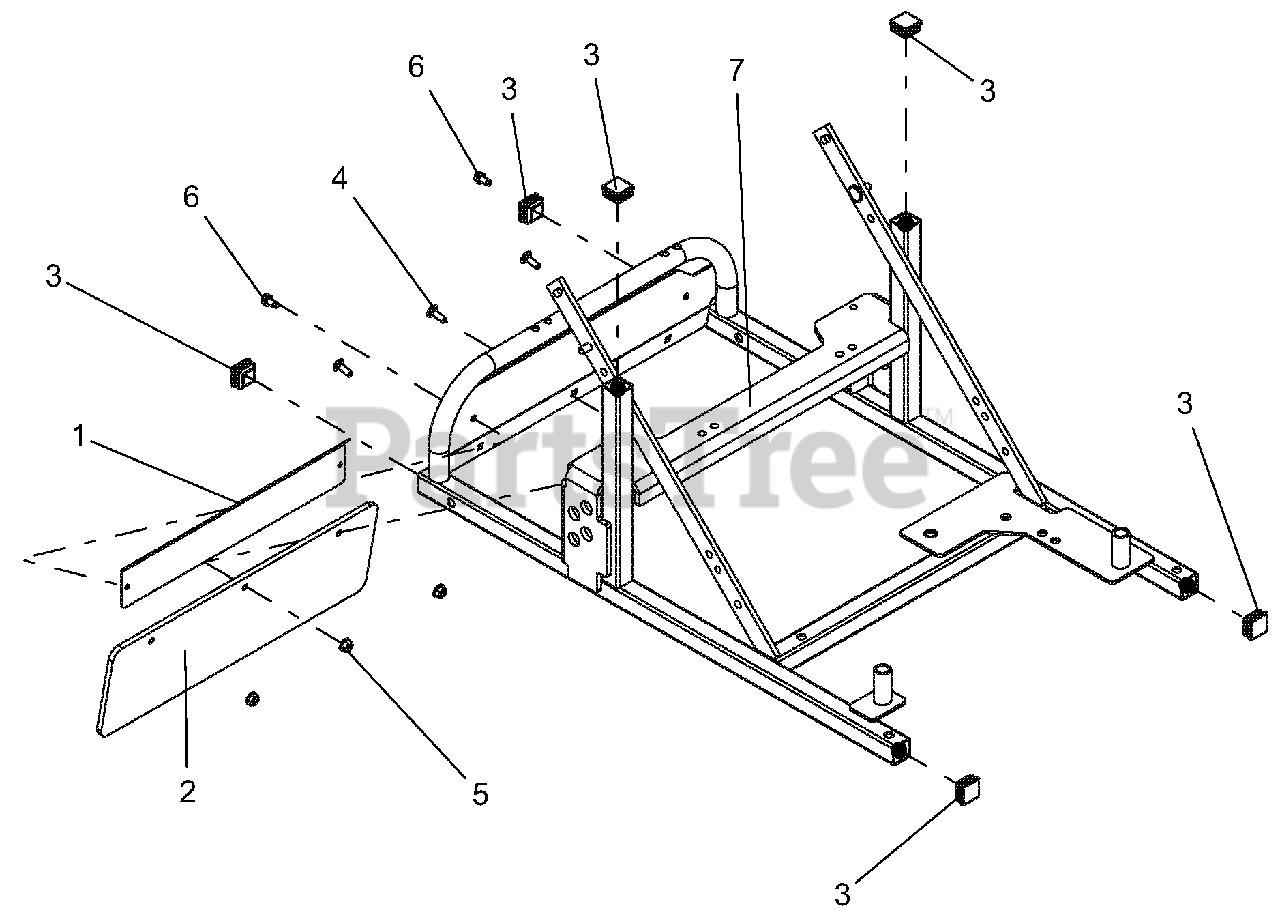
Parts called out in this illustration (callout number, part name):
1	BACKER, GRAVELY
2	GUARD, RUBBER DEBRIS
3	CAP PLUG FOR 1" TUBE 14GA
4	@BLT-RDHDSQNK .25-20X.75 G5YZ
5	@NUT-LK-TOP-FLG .25-20 YWZC
6	SCR-TAP .25-20X.50 HWH TR YWZ
7	WMT-HWM FRAME PLAIN
